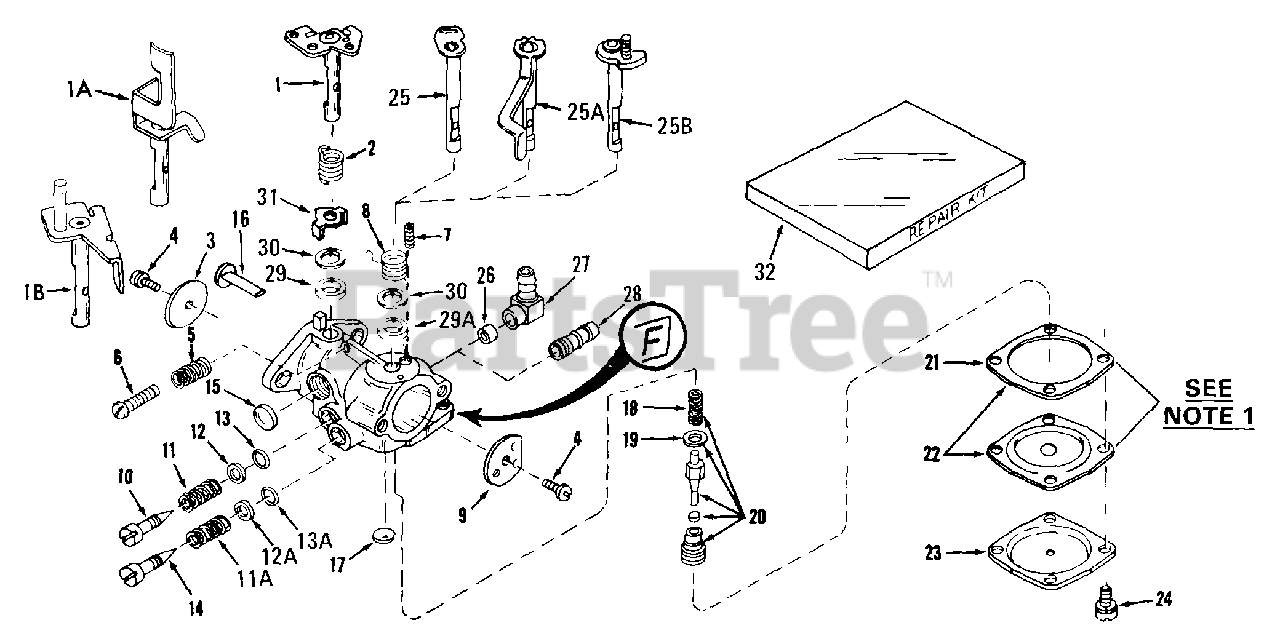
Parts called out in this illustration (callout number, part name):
1	"Shaft & Lever Assy., Throttle
2	Spring, Throttle return
3	Shutter, Throttle
4	Screw, Throttle & Choke shutter
5	Spring, Regulating screw
6	Screw, Idle regulating
8	Spring, Choke return
9	Shutter, Choke
10	Screw, Idle adj.
11	Spring, Adj. screw
12	Washer, Adj. screw
13	"O" Ring, Adj. screw
15	Plug, Welch
18	Spring, Valve
19	Gasket, Valve seat
20	Inlet Needle, Valve, Seat & Gasket As sy.
21	Gasket, Diaphragm
22	Diaphragm Assy. (Includes No. 21)
23	Cover, Diaphragm
24	Screw, Cover
25	Shaft & Lever Assy., Choke
27	Fitting, Fuel inlet
32	Repair Kit
